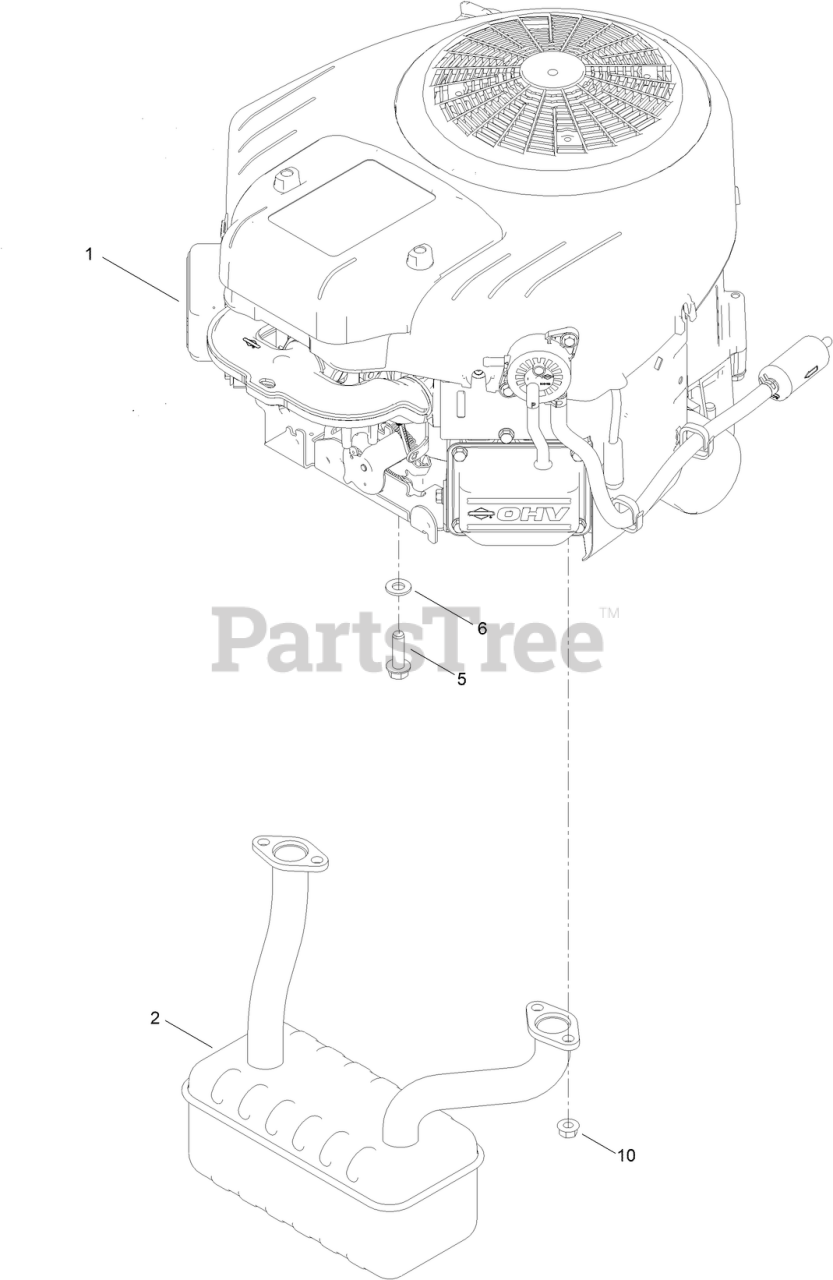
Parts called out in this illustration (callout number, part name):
1	ENGINE - BS EXI
2	MUFFLER
5	SCREW-THD
6	WASHER-FLAT
10	NUT-HF
